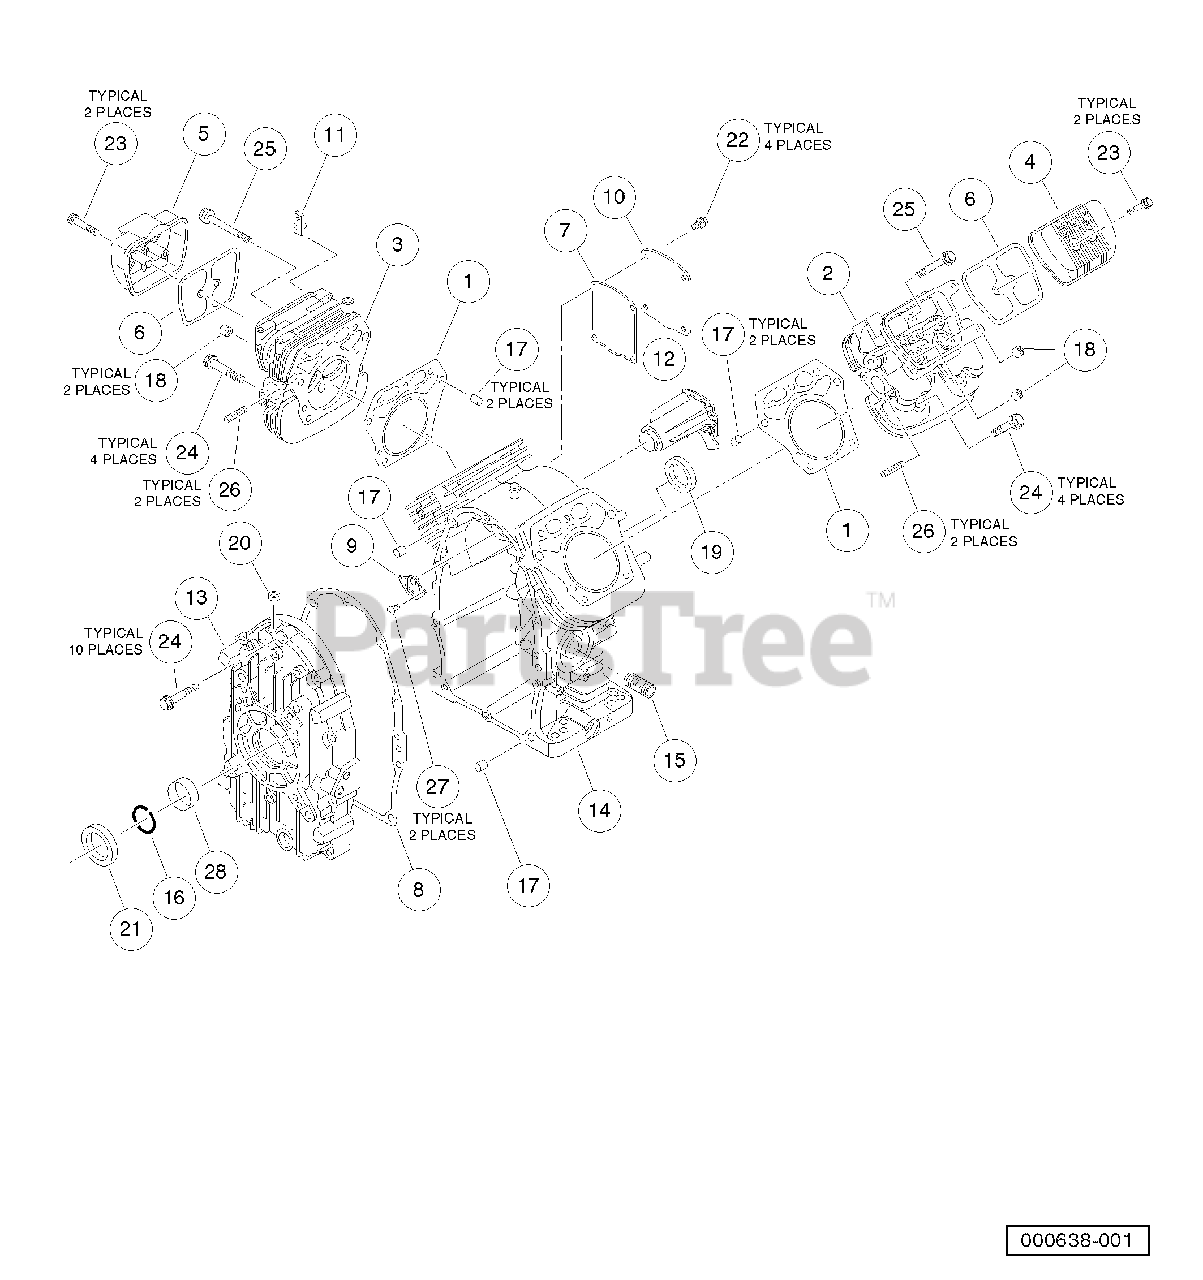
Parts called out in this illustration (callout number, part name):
1	Gasket, Head, Cyl, Fh
2	Head, Cyld 1, Fh
3	Head, Cyld 2, Fh
4	Cover, Rocker, Cyld 1, Fh
5	Cover, Rocker, Cyld 2, Fh
6	Gasket, Rocker, Cover, FH
7	Gasket, Breather, Fh
8	Gasket, Cover, Crank, Fh
9	Valve, Assy, Reed, Fh
10	Cover, Crkcase, Comp, Fh
11	Pipe, Head, Comp, Clyd, Fh
12	Pipe, Crkcase, Comp, Fh
13	Cover, Crankcase, Fh
14	Crankcase, Comp, Fh
15	Nipple, Oil Filter, Fh
16	Ring, Snap, Fh
17	Pin, Head, Fh
18	Seal, Oil, Valve, Fh
19	Seal, Oil, Crank, Rear, Fh
20	Seal, Oil, Governor, Fh
21	Seal, Oil, Crank, Front, Fh
22	Bolt, Flg, M6 X 1.0 X 12
23	Bolt, Flg, M6 X 1.0 X 40
24	Bolt, Flg, M8 X 1.25 X 50
25	Bolt, Flg, M8 X 1.25 X 75
26	Stud, M8 X 1.25, Exhaust, Fh
27	Screw, Pan, Governor, Fh
28	Bushing, Main, Fh
